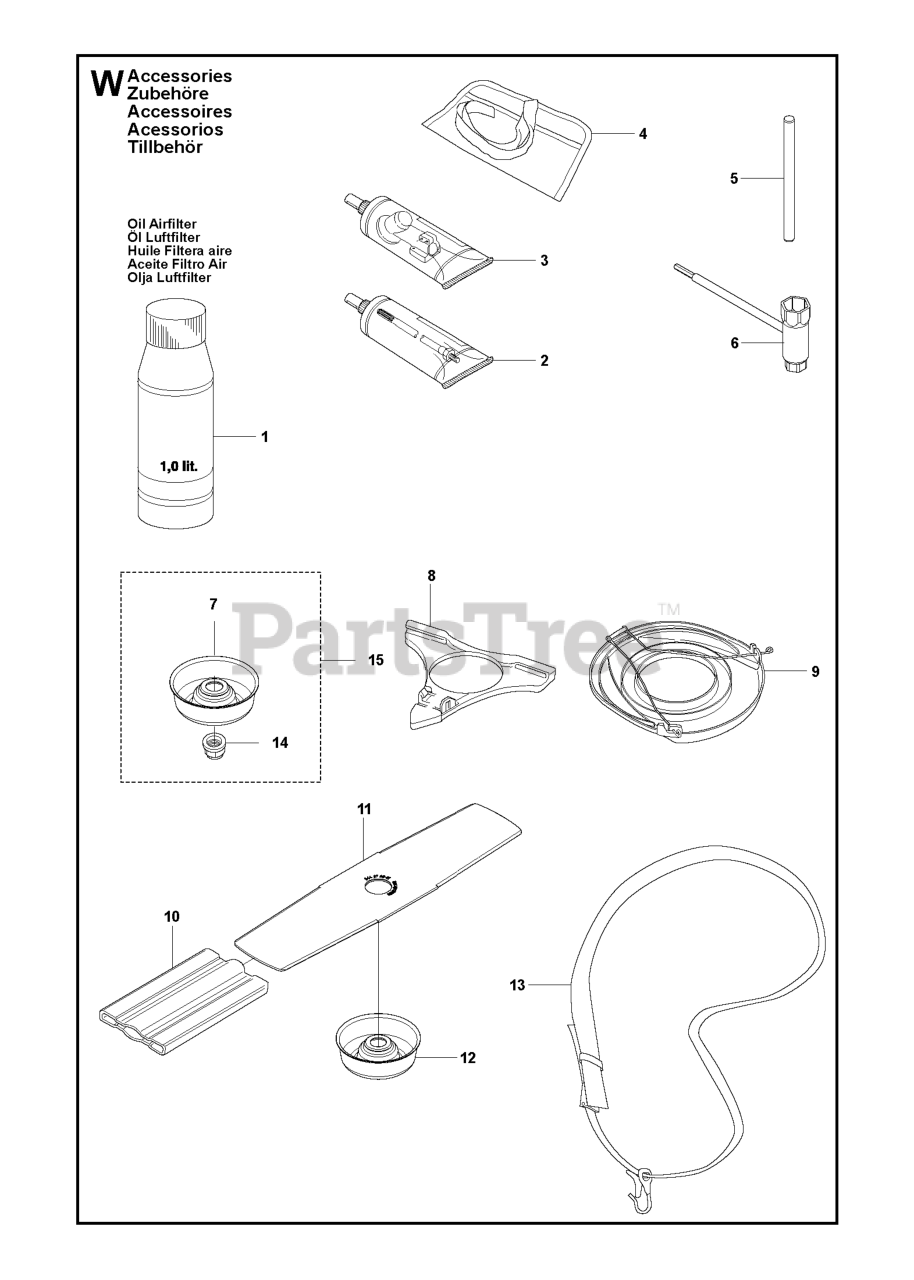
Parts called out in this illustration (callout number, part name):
1	Air Filter Oil 1l.
2	DRIVE SHAFT GREASE (200 G)
3	BEVEL GEAR GREASE
5	LOCKING PIN
6	RP COMBI TOOL
7	SUPPORT CUP
8	TRANSPORT GUARD
9	BLADE GUARD TRANSPORT
12	SUPPORT CUP
13	Harness-w/o warning
